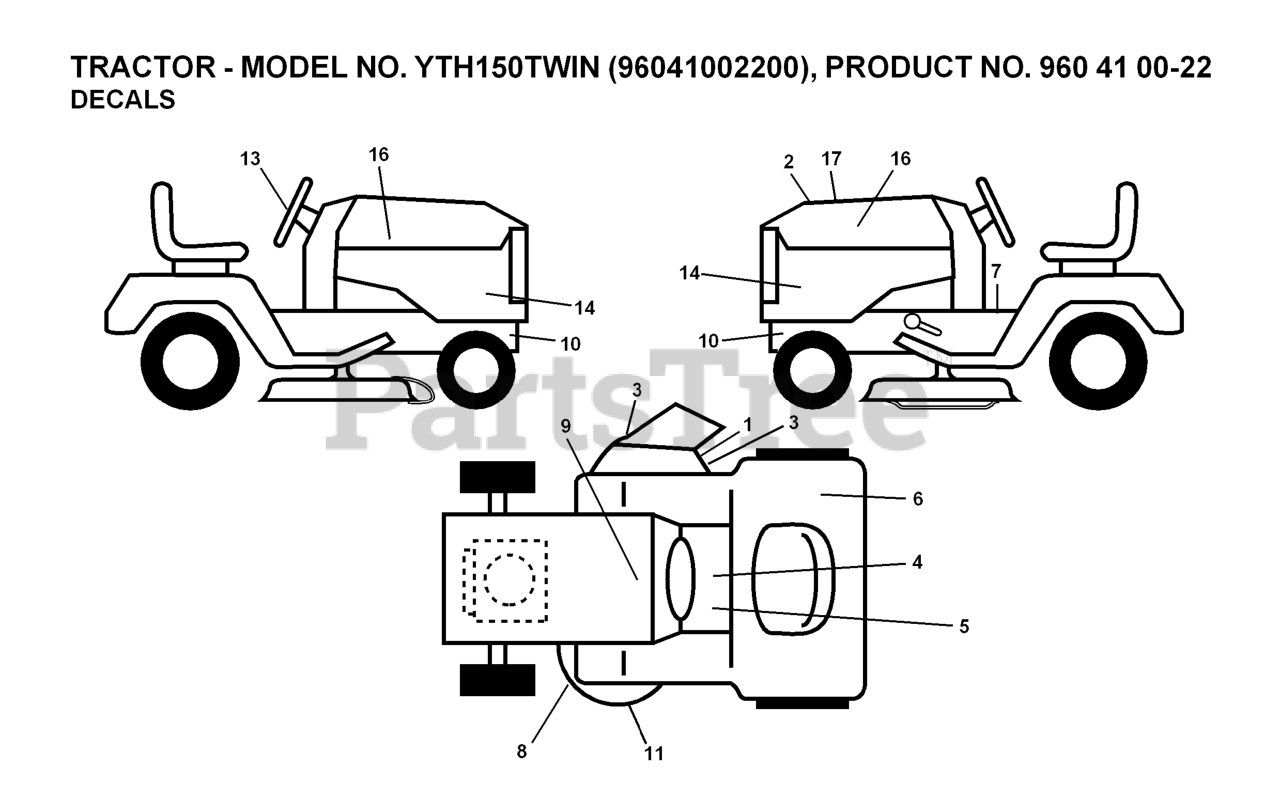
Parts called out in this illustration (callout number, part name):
1	DECAL.INTERNATIONL.CUTFINGER
2	DECAL.HOOD.TOP.INSERT.
3	DECAL, DEFLECT WARNING
4	DECAL PARK BRAKE
5	LABEL
6	Decal, Fender 100 DB/CE
7	DECAL
8	DECAL V BELT SCHEMATIC
9	DECAL BTRY SYMBOLS
13	DECAL.WHEEL.STRG.LGN.H
16	DECAL.HOOD.NAMELOGO.HUSQ
